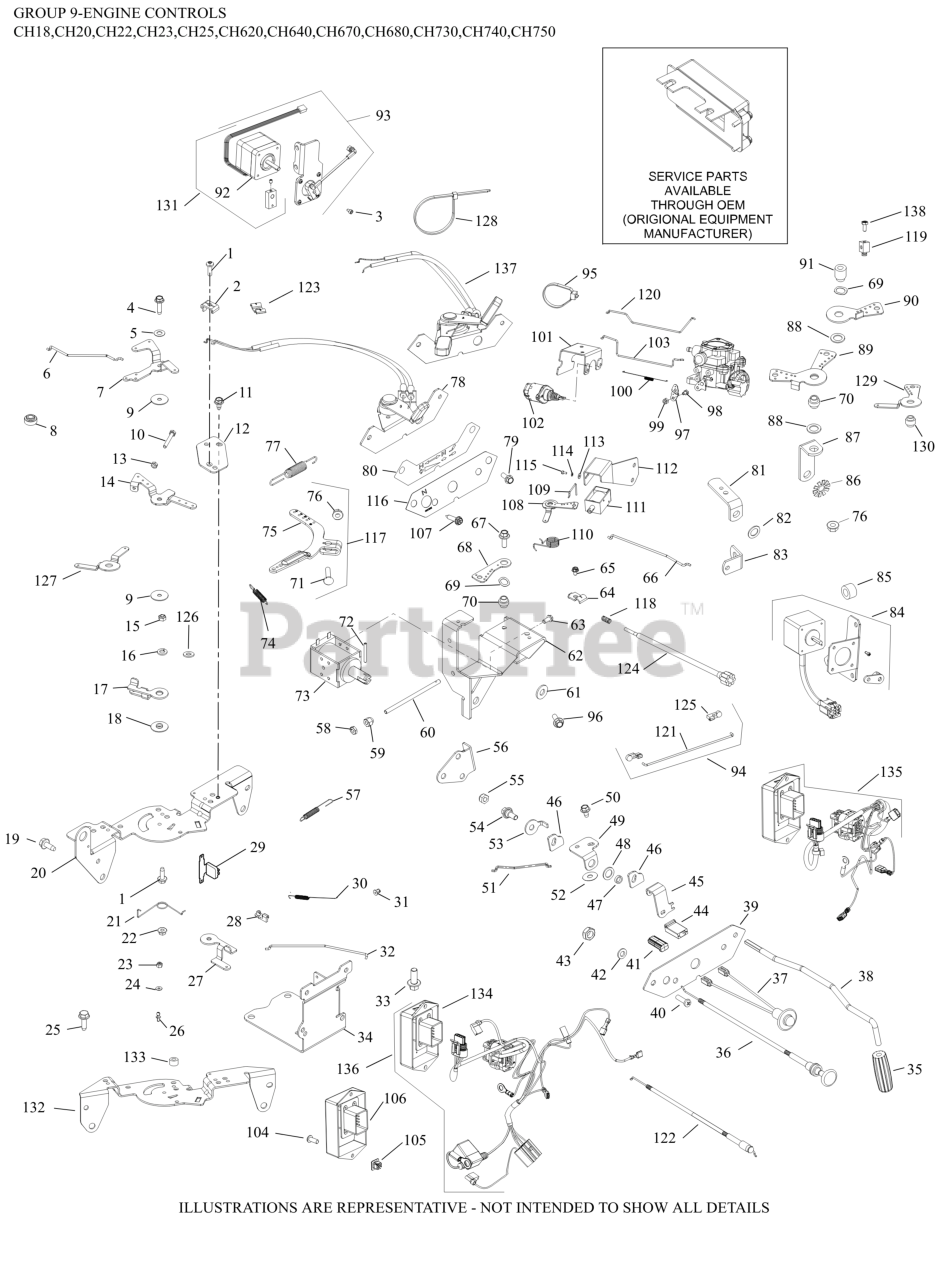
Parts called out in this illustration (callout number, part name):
1	SCREW, THREAD FORMING
2	CLAMP, CABLE-(#2523753S)
4	SCREW, THD FRM-USE 25 086 473-S
5	WASHER, SPRING 1/4"
6	LINKAGE, CHOKE
7	LEVER, CHOKE
9	WASHER, FLAT 5.5 MM
10	SCREW, CAP M4X.7X30
12	BRACKET, CABLE SUPPORT
13	NUT, M4X0.7
14	LEVER, THROTTLE CONTROL
15	NUT, FLG M5X.8
16	WASHER, SPRING LOCK 1/4"
19	SCREW, THREAD FORMING
20	BRACKET, CONTROL-(#24126263S)
22	NUT, LOCK M5X.8
27	LEVER, THROTTLE ACTUATOR
28	BUSHING, THROTTLE LINKAGE
30	SPRING, LINKAGE
31	BUSHING, LINKAGE RETAINING
32	LINKAGE, THROTTLE
50	SCREW, THREAD FORMING
57	SPRING, THROTTLE LIMITER
71	BOLT, RD HD SQ NECK M6X1.0X25
75	LEVER, GOVERNOR - (#2409069S)
76	NUT, FLG M6X1.0
77	SPRING, GOVERNOR (BLACK)
80	DECAL, CONTROL PANEL
107	SCREW, HEX WASHER HI-LO
117	LEVER, GOVERNOR ASSEMBLY
137	CABLE, CONTROL ASSEMBLY
